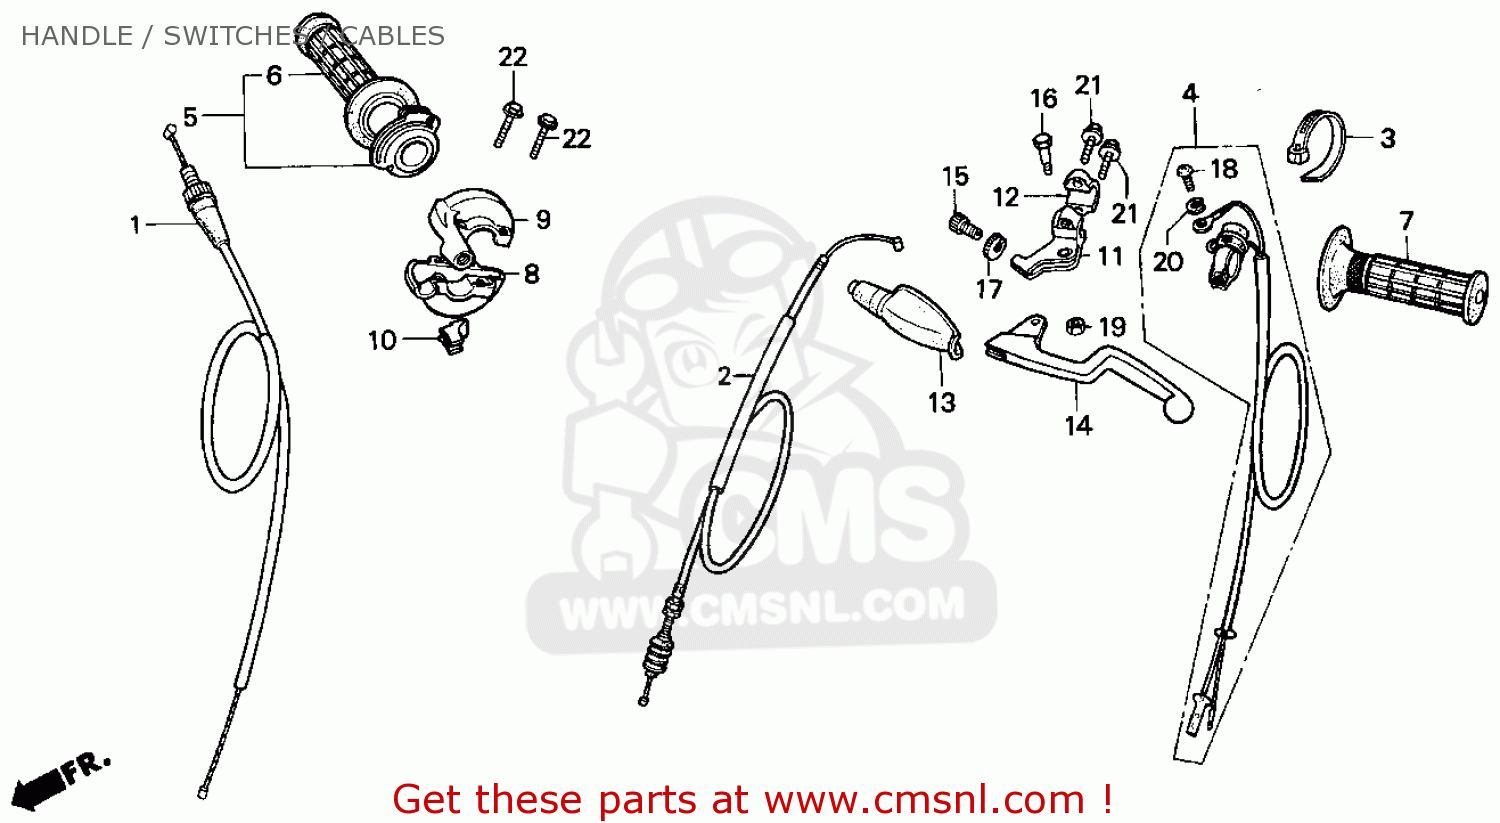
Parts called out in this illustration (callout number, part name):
1	CABLE COMP,THROT.
2	CABLE COMP.,CLUTC
3	BAND,BI WIRE
4	SW.ASSY.,KILL.
5	GRIP COMP.,THROTT
6	GRIP,R.HANDLE
7	GRIP,L.HANDLE
8	HOUSING,A GRIP
9	HOUSING,B GRIP
10	SLIDER THROT CABL
11	BRKT,L.HNDL.LEVER
12	HOLDER L LEVER BR
13	COVER,L.HNDL.LEV
14	LEVER L,STRG HNDL
15	BOLT,WIRE ADJ
16	BOLT HNDL PIVOT
17	NUT,FIXING
18	SCREW,PAN 4X12
19	NUT,HEX 6MM
20	WASHER,SPG.,4MM
21	BOLT,FLANGE,6X22
22	BOLT,FLANGE,6X25
